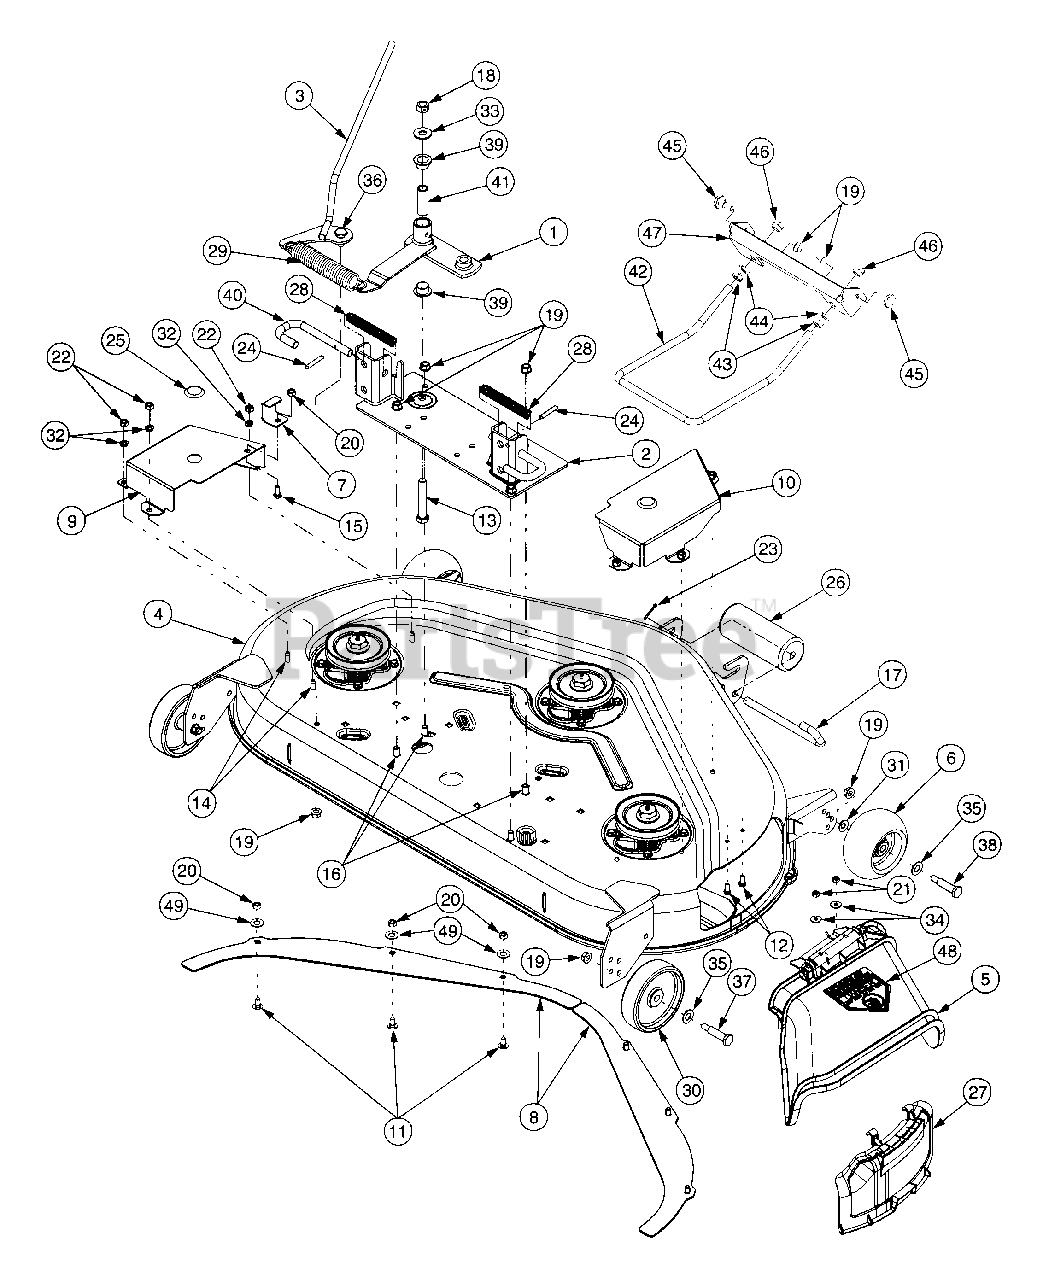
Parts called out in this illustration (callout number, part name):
2	Plate Assy, Mounting
3	Handle, Tension
4	Deck Housing Assembly
5	Chute Assembly, Discharge
6	Wheel, Deck w/Fitting
7	Bracket, Stop
8	Baffle, Skirt
9	Belt Cover, LH
10	Belt Cover, RH
11	Bolt, Carriage, 5/16-18 x .62
12	Screw, Hex Cap, 1/4-20 x .62
13	Screw, Hex Cap, 1/2-20 x 3.0
14	B Screw, Self Tap, 5/16-18 x .75
15	Screw, Hex Cap, 5/16-18 x .75
16	Bolt, Carriage, 3/8-16 x .75 GR5
17	Pin, Roller, 1/2 Dia x 7.31
18	Nut, Hex Lock, 1/2-20
19	Nut, Flange Lock, 3/8-16
20	Nut, Flange Lock, 5/16-18
21	Nut, Hex, 1/4-20 GR5
22	Nut, Hex, 5/16-18, GR5
23	Pin, Cotter, 1/8 Dia x 1
24	Pin, Spiral Spring, 3/16 Dia x .75
25	Button Plug
26	Front Roller
27	Plug, Mulch
28	Spring, Comp, .66 OD x 1.8
29	Spring, Ext, .162 Dia x 1.25 OD
30	Wheel, Deck, 5.0 x 1.38
31	Washer, Bell. .401 x .870 x .063
32	Washer, Lock, 5/16
33	Washer, Flat, 1/2 x 1.25 x .10
34	Washer, Bell, .265 x .75 x .062
35	Washer, Flat, .510 x 1 x .060
36	Bolt, Shoulder, .498 Dia x .340
37	Screw, Shoulder, .498 x 1.635
38	Bolt, Shoulder
39	Bearing, Flange, 3/4 ID x .52 LG
40	Pin, Mower Support
41	Spacer, .5 OD x .75 x 2.07 Lg
42	Rod, Front Lift
43	Nut, Hex Jam, 1/2-13 GR5
44	Washer, Lock, 1/2
45	Bolt, Shoulder, .50 Dia. x .494 Lg
46	Nut, Hex Insert Lock, 1/2-13
47	Bracket, Front Lift
48	Graphic, Danger
49	Washer, Flat, .474 x .88 x .064
